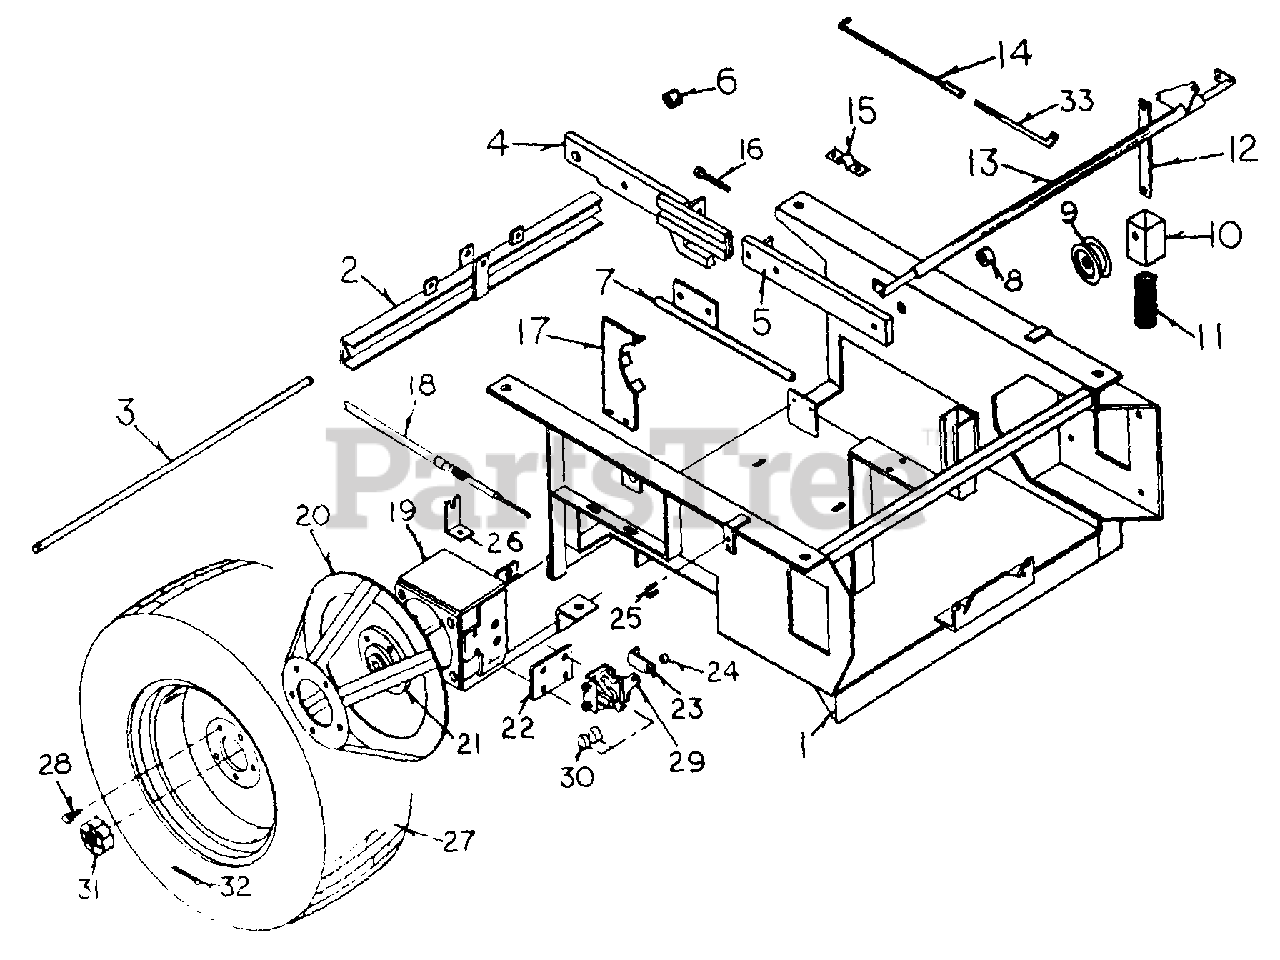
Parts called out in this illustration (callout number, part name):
1	BASE
2	LIFT BAR
3	CROSS BAR PIN
4	DECK LIFT ARM - Front Adjustable R.H.
5	DECK LIFT ARM - Back
6	BUSHING - Long
8	BUSHING - short
10	SPRING LOADED IDLER MOUNT
12	PIVOT BAR LINKAGE
13	BRAKE CLUTCH ROD
14	BRAKE ROD - adjustable
15	CROSS ROD BEARING
16	DECK ARM ADJUSTING BOLT
19	AXLE
21	HUB - 5 BOLT
22	BRAKE CALIPER MOUNT
23	CABLE END
24	BUSHING
25	CLAMP
26	CABLE DEAD HEAD
27	TIRE ASSEMBLY - 20 x 8.00-10
27	TIRE ASSEMBLY - 20 x 10.00-10
29	BRAKE CALIPER - L.H.
29	BRAKE CALIPER - R.H.
32	COTTER KEY
